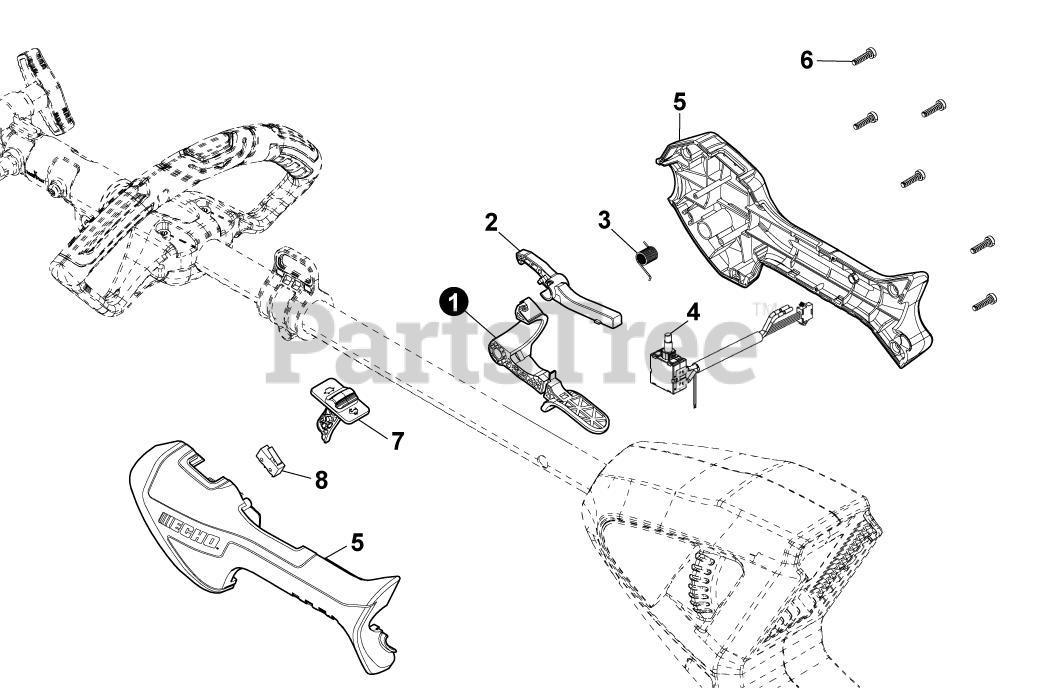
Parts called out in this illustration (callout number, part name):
2	LEVER, INTERLOCK
3	SPRING, TORSION
4	SWITCH, SPEED CONTROL
5	HANDLE ASSY
6	SCREW
7	KNOB, SWITCH
8	SWITCH, MICRO
